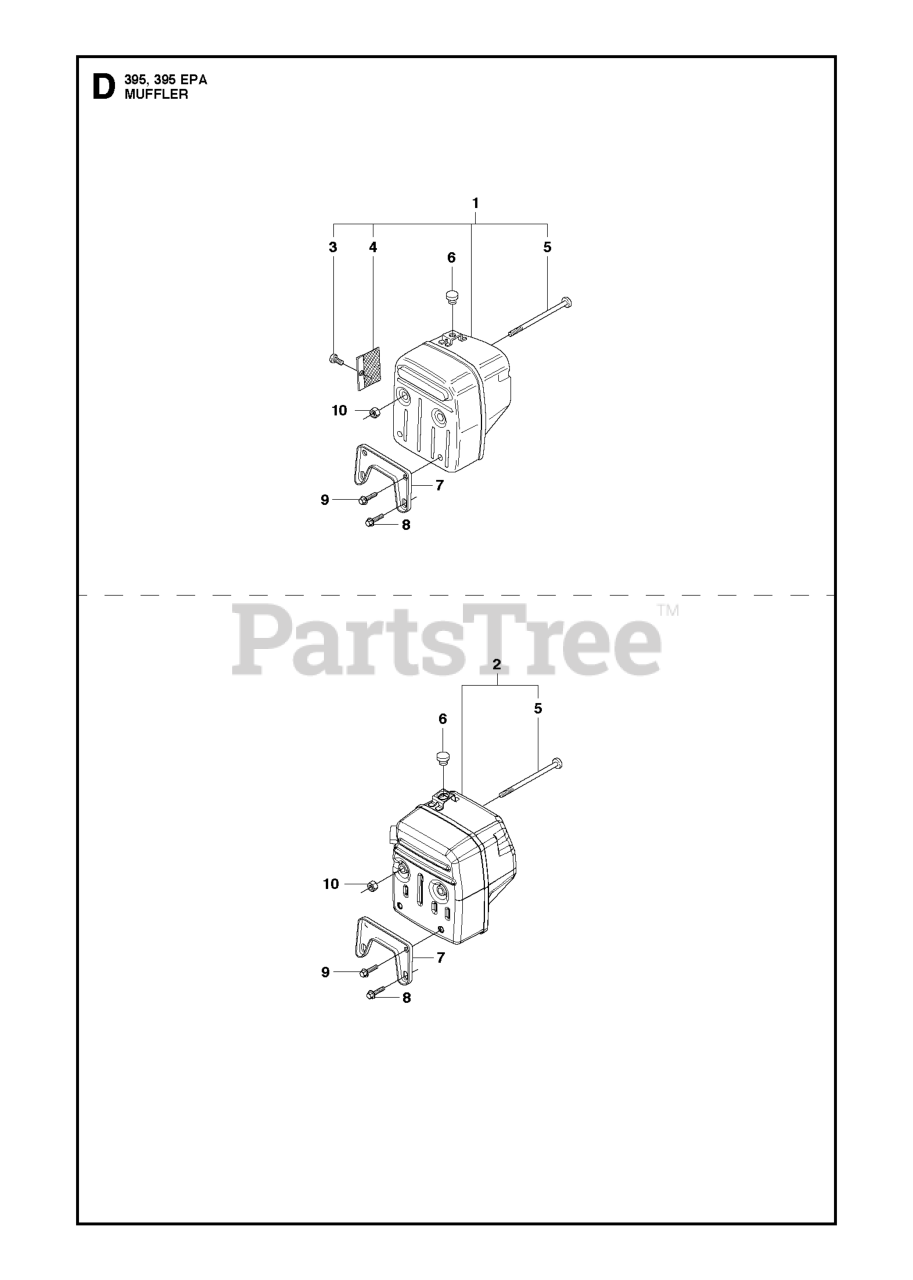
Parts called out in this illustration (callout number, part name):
1	MUFFLER
2	Muffler
2	MUFFLER
6	RUBBER BUMPER
9	SCREW IHSCFM
